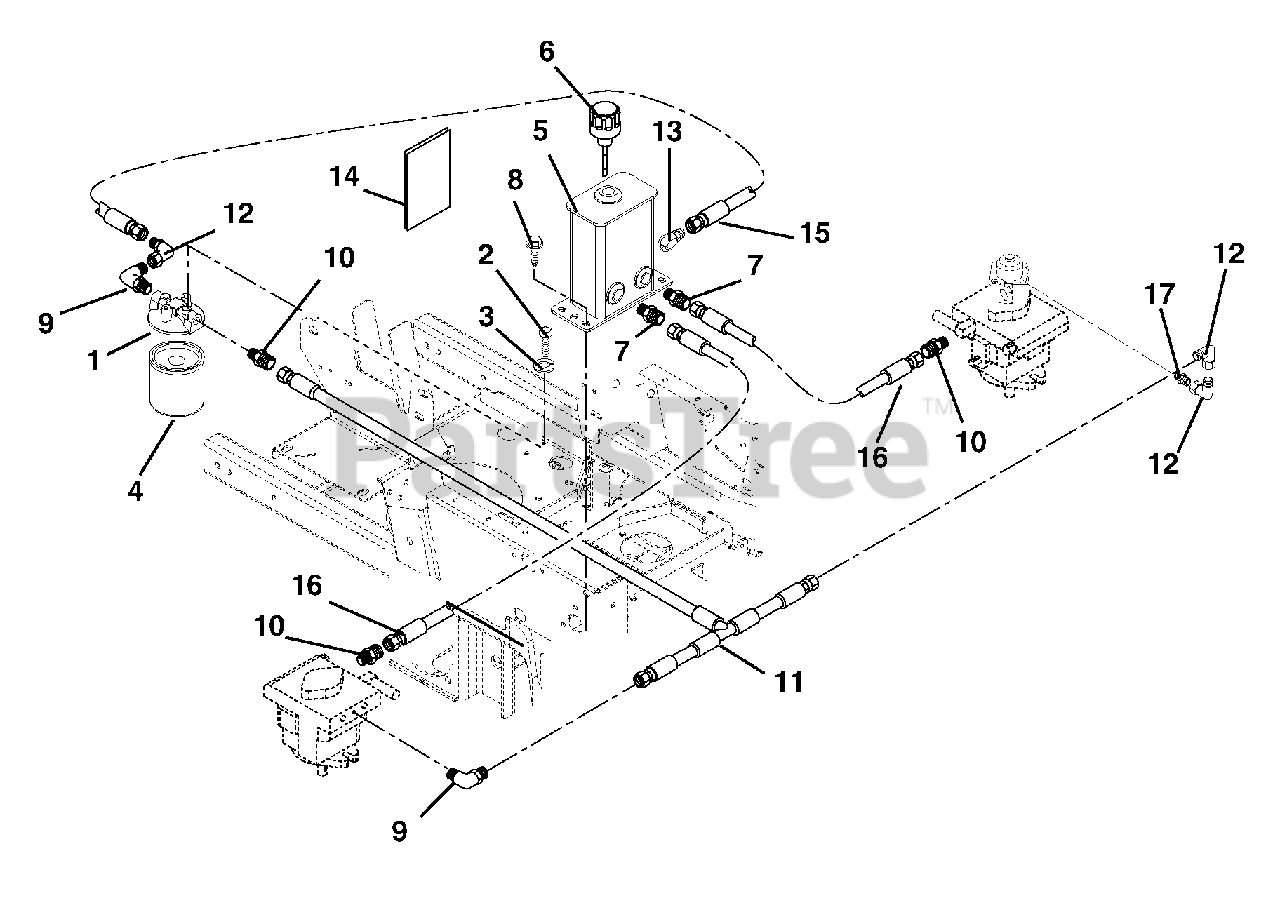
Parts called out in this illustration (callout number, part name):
1	Head, Filter
2	Bolt, Hex .25-20 x .50 Grade 5
3	Washer, Locking .25 x .062
4	Oil Filter
5	Tank, Hydraulic
6	Hydraulic Tank Dipstick
7	Adapter, Straight
8	Screw, Tapping .38-16 x .50 Hex Washer Head
9	Adapter
10	Adapter, Pipe .56-18 "O" Ring to .56-18
11	Hose, Tee Assembly .38"
13	Fitting, Hydraulic 45 Degree
14	Shield, Heat 5.50 x 4.50
15	Hose,Hydraulic
16	Hose, Hydraulic
